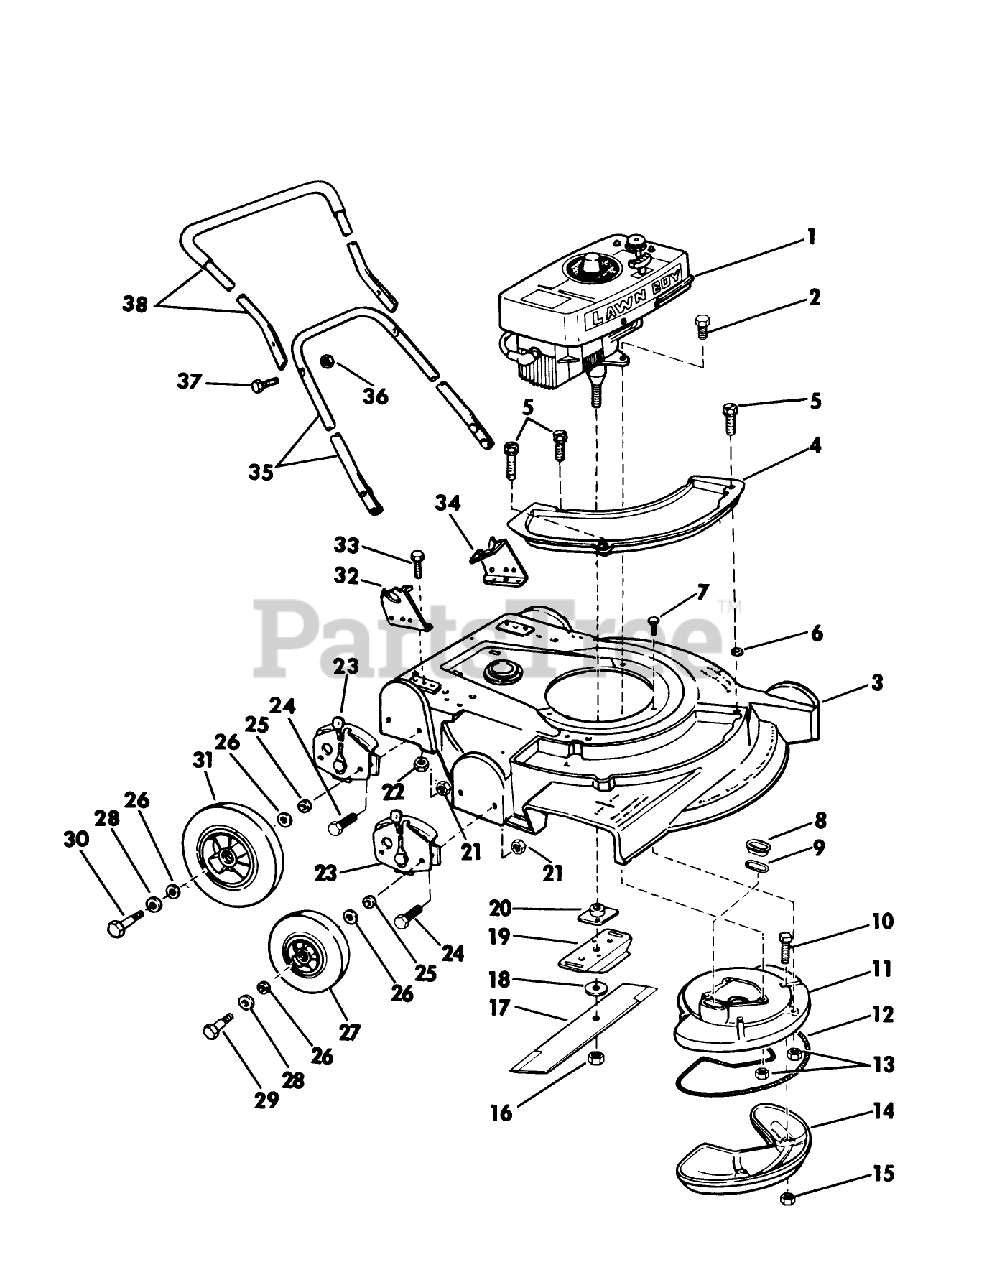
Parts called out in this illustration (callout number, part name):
5	SCREW SEMS TRM HEX HD
9	GASKET S
15	LOCKNUT E
16	NUT-BLADE
20	PLATE AND COLLAR ASM
25	WASHER WROUGHT
29	BOLT WHEEL
38	Handle Grip Assy. Top
